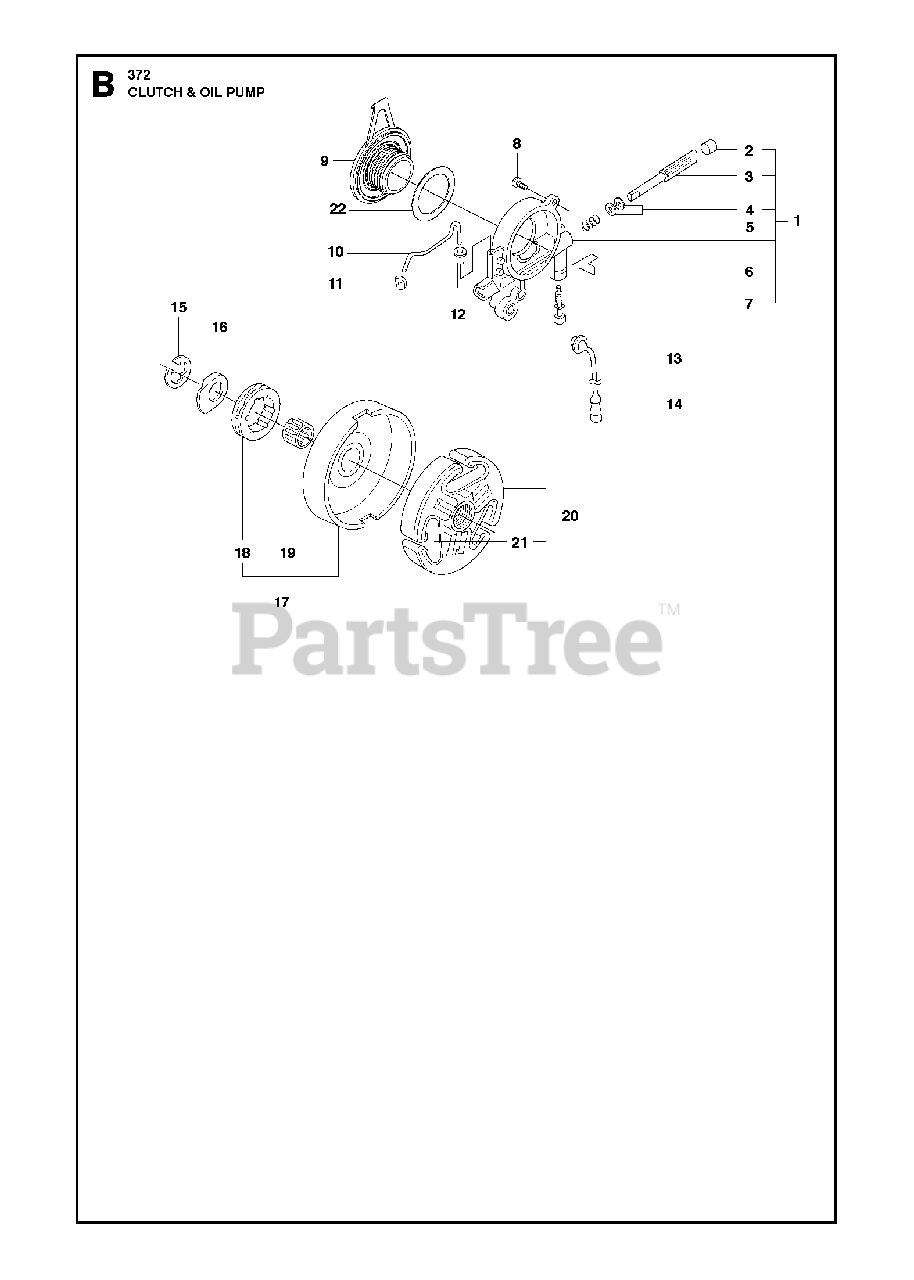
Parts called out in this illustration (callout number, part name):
1	OIL PUMP
2	PLUG
3	PUMP PISTON
4	WASHER 6.1X9
5	SPRING
6	SPRING CLIP
7	SCREW
8	SCREW MC6S 5X16
9	OIL PUMP DRIVE
14	OIL SCREEN
15	RETAINING RING
17	CLUTCH DRUM
18	68210 RIMSPROCKET
18	Power Mate Rim
19	CLUTCH DRUM BEARING
20	CLUTCH
